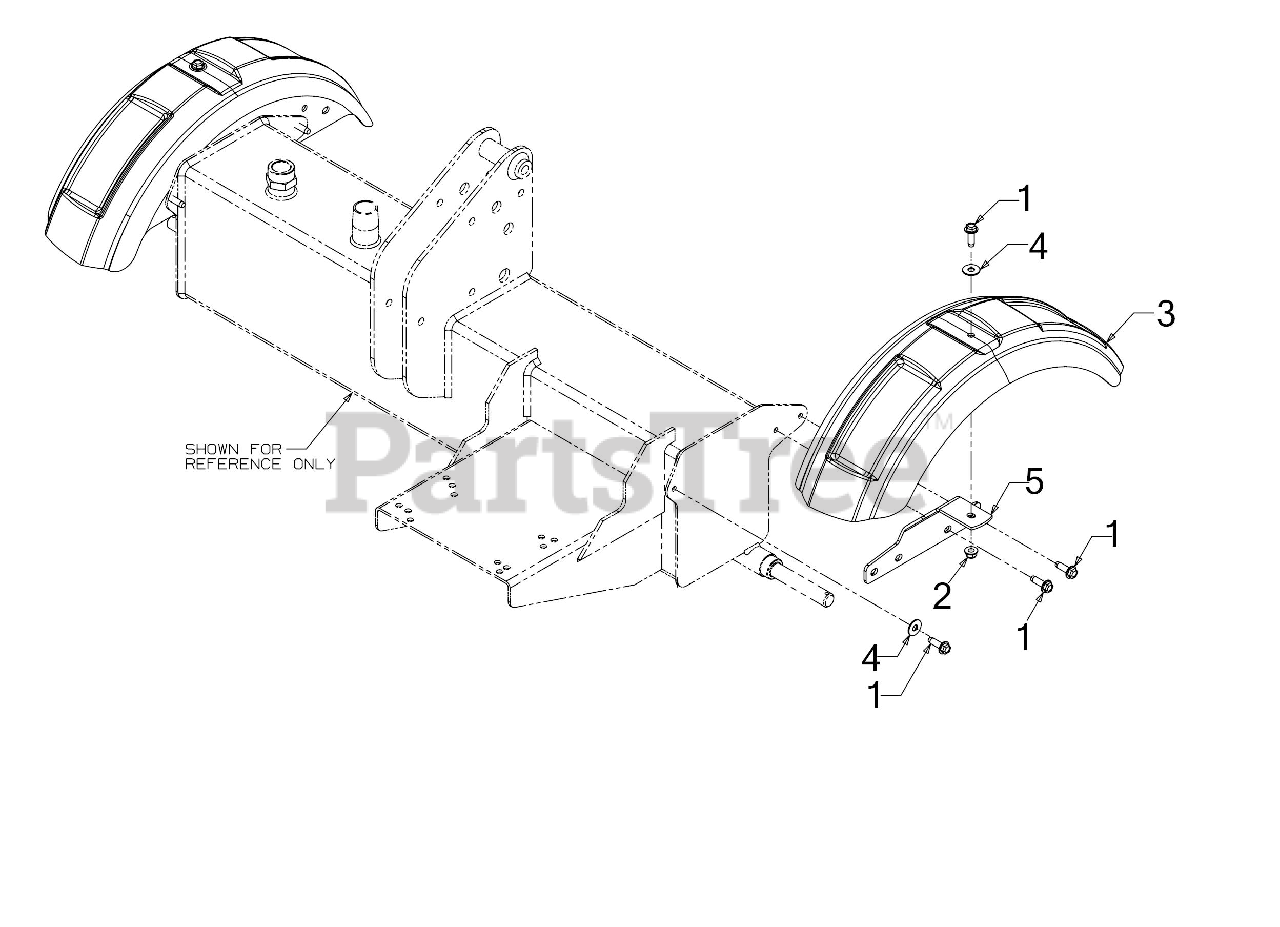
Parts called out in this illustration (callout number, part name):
1	SCREW 5/16-18 x 1.00
2	FLANGE LOCK NUT 5/16-18
3	LOGSPLITTER FENDER
4	FLAT WASHER
5	MOUNTING BRACKET
